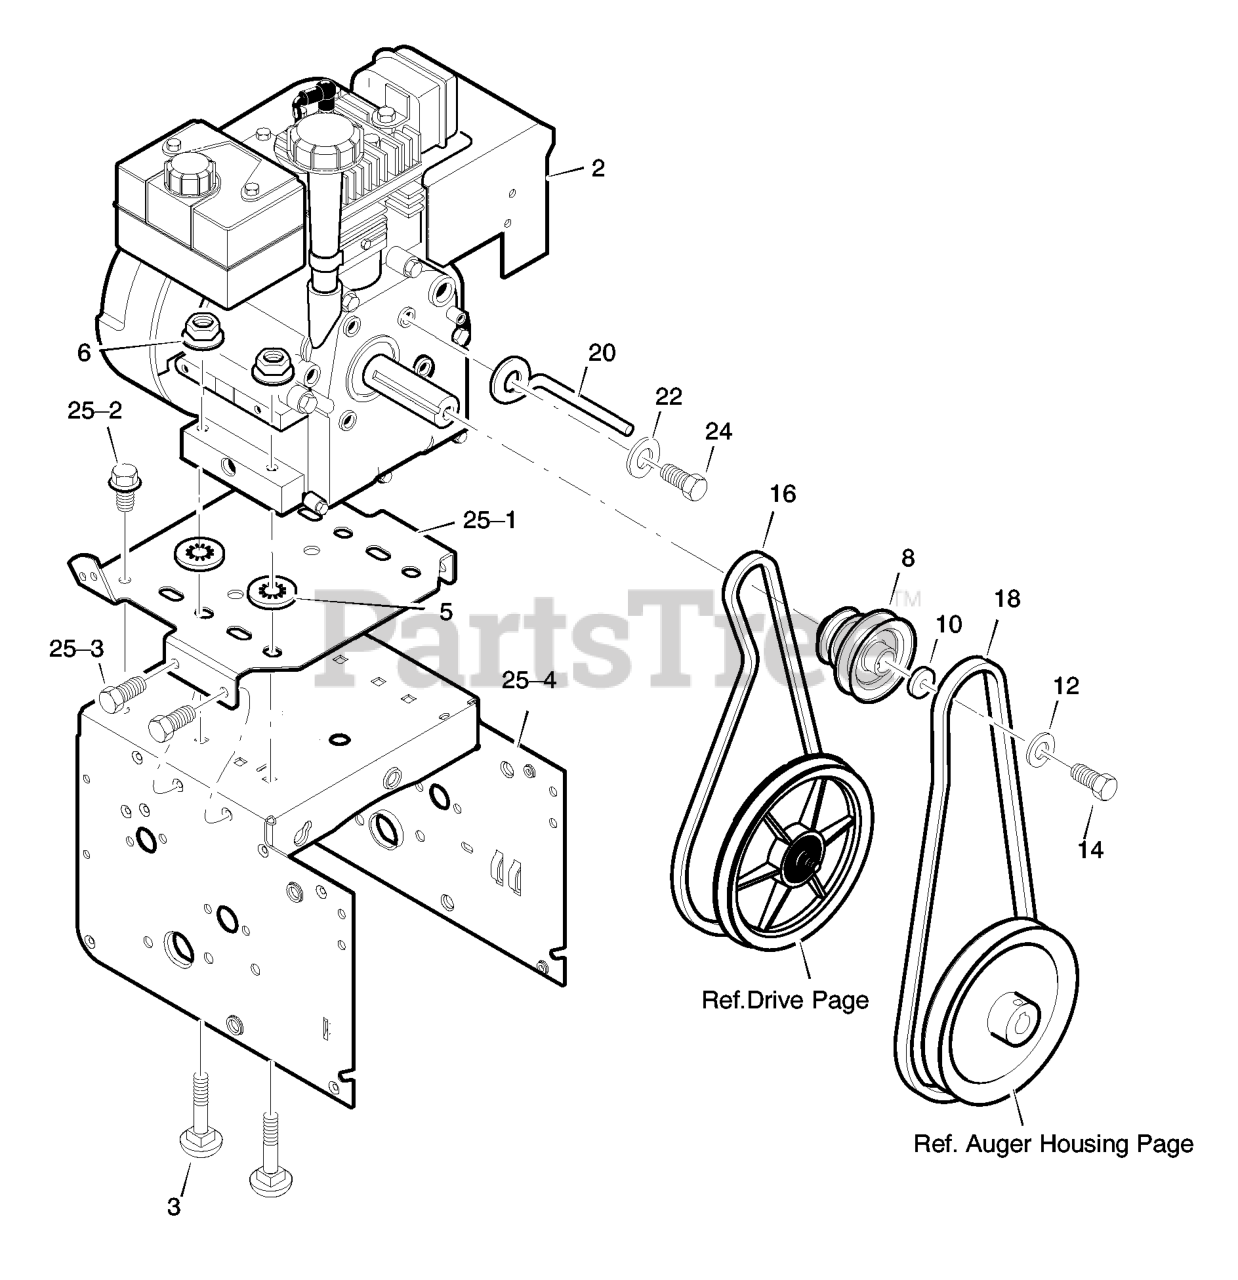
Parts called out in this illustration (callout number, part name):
2	ENGINE
3	BOLT, CARRIAGE 5/16-18
5	RETAINER, PUSH
6	NUT, HEXWDFLLK 5/16-18
8	PULLEY, ENGINE
10	WASHER
12	WASHER,HVSPTLK .38ID
14	SCREW, 3/8-24 x 1.00
16	BELT, V
18	BELT, V 4L
20	GUIDE, BELT
22	WASHER, SPTLK .31X.58X.08
24	SCREW, 5/16-24 x 0.75
25	FRAME, MOTORBOX (5-11HP)
25-1	PLATE, ENGINE MOUNT
25-2	SCREW, TAP 1/4-20 X .63
25-3	SCREW, TAP 5/16-18 X .50
25-4	FRAME, MOTOR BOX
